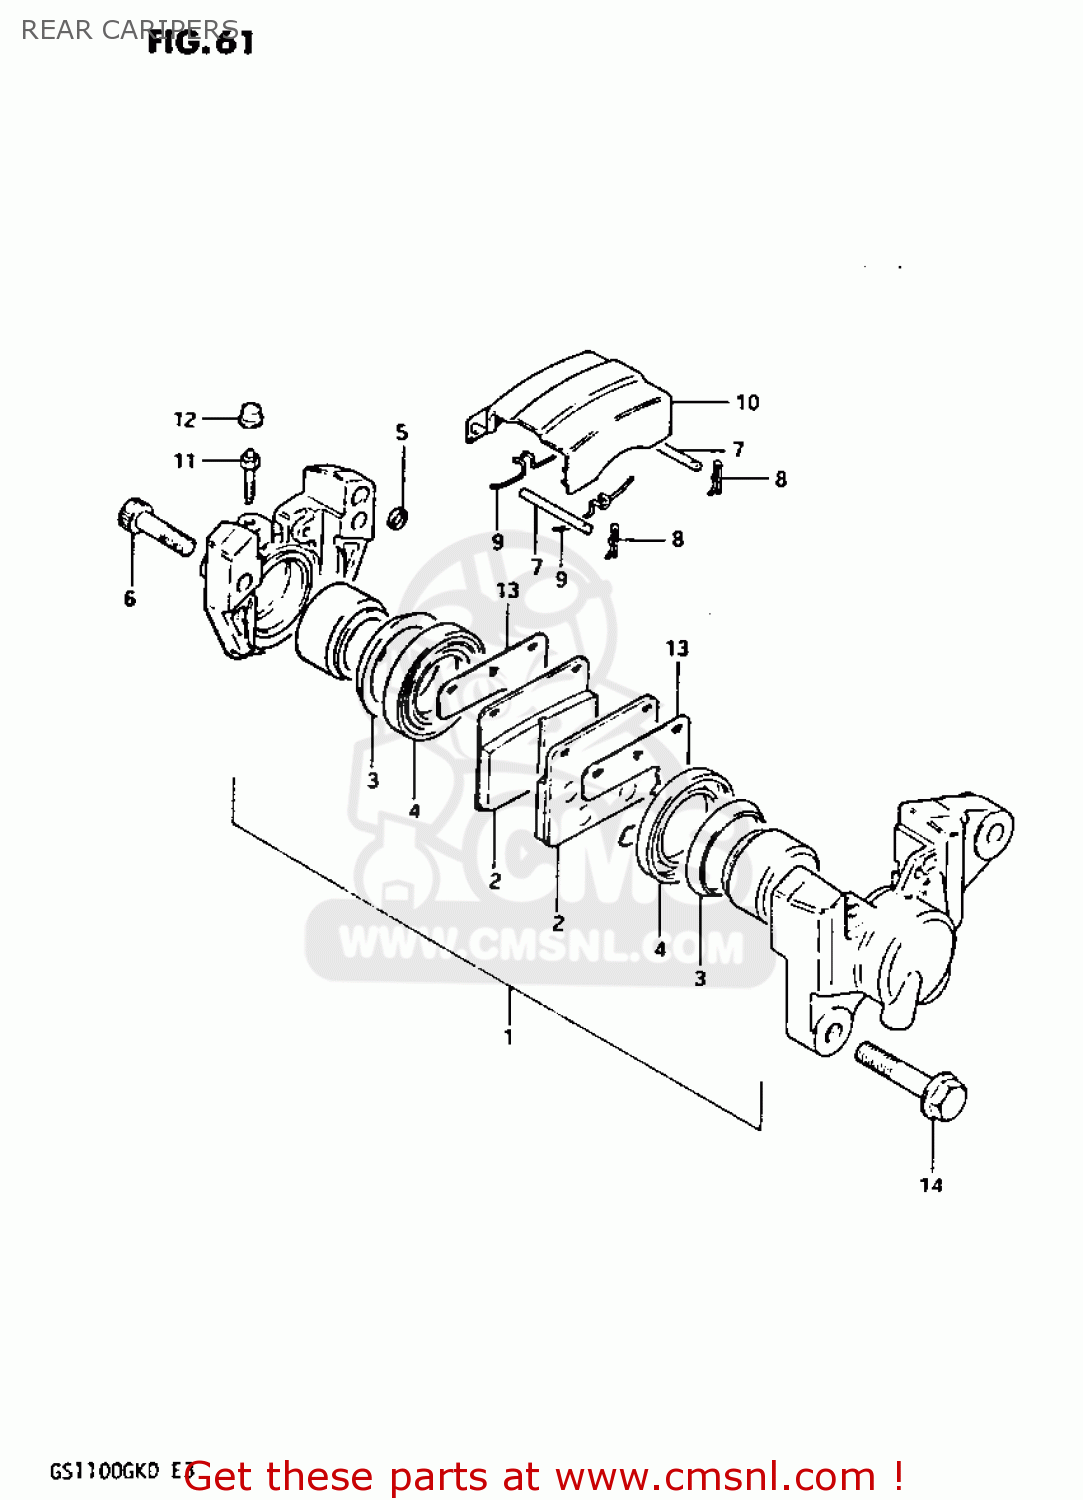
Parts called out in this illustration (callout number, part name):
1	PISTON/PAD SET
2	PAD,BRAKE (MCA)
3	SEAL,FR CALIPE
4	BOOT,PISTON
5	SEAL,JOINT
6	BOLT,CALIPER HOUSING
7	PIN,PAD
8	CLIP,PAD PIN
9	SPRING
10	COVER,DUST
11	BLEEDER
12	CAP,BREATHER
13	SHIM,RR CALIPER
14	BOLT
